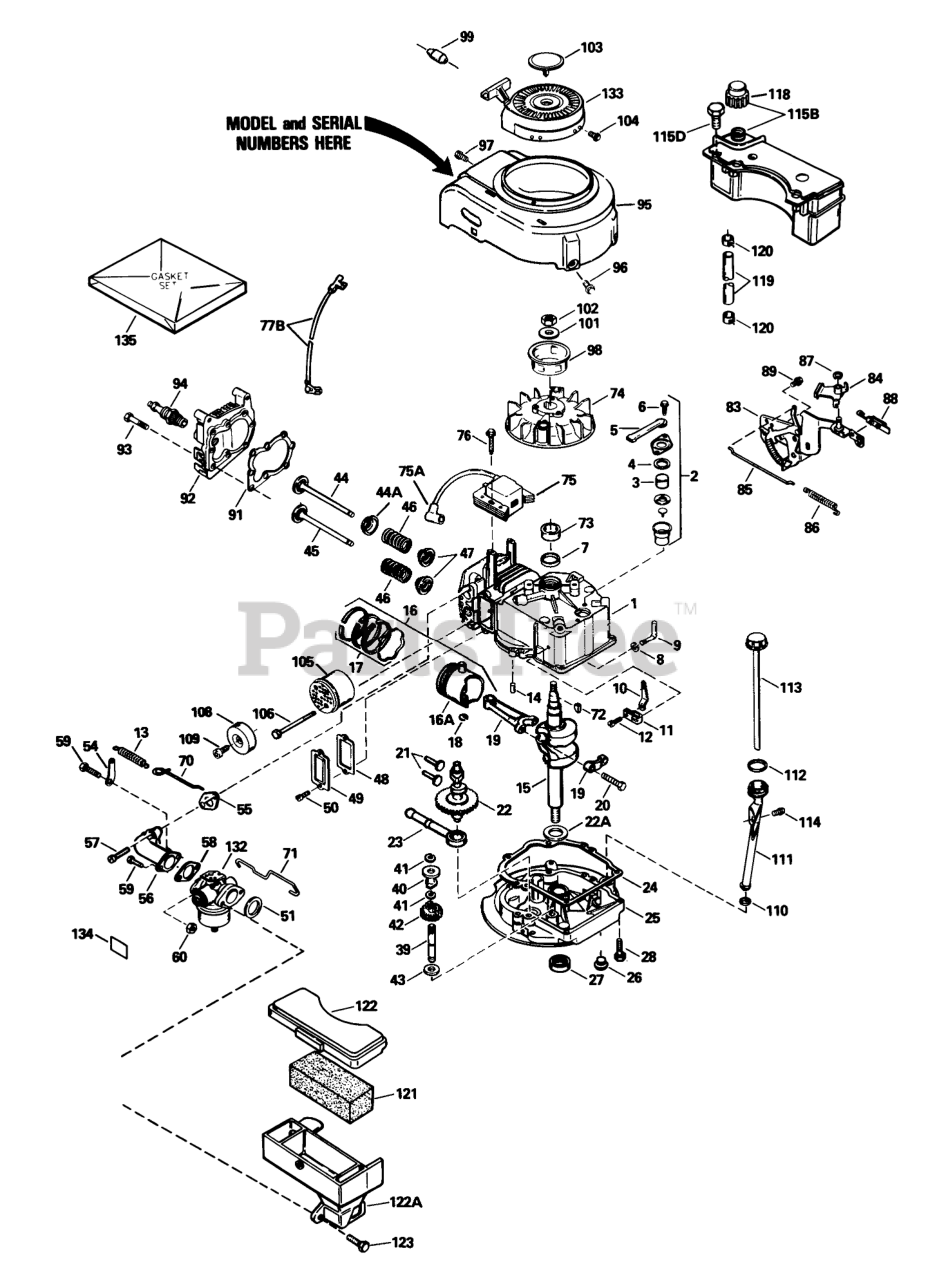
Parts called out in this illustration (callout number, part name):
1	Cylinder Assembly (Incl. Ref. #4, 6, 7 & 14)
2	Breather Assembly (Incl. Ref. #3 thru 6)
3	Element-Breather
4	Gasket-Breather
5	Tube, Breaker
6	Screw (10-24 x 9/16)
7	Seal-Oil
8	Washer-Flat
9	Rod, Governor (Incl. Ref. #8)
10	Governor Lever
11	Clamp-Lever, Governor
12	Screw
13	Spring Governor
14	Pin-Dowel
15	Crankshaft
16	Piston, Pin & Ring Assembly (Std.) (Incl. Ref. #16A, 17 & 18)
16	Piston, Pin & Ring Assembly (.010 oversize) (Incl. Ref. #16A, 17 & 18)
16	Piston, Pin & Ring Assembly (.020 oversize) (Incl. Ref. #16A, 17 & 18)
16A	Piston & Pin Assembly (Std.) (Incl. Ref. #18)
16A	Piston & Pin Assembly (.010 oversize) (Incl. Ref. #18)
16A	Piston & Pin Assembly (.020 oversize) (Incl. Ref. #18)
17	Piston Ring Set Std.
17	Piston Ring Set .010 O.S.
17	Piston Ring Set .020 O.S.
18	Ring-Retaining, Piston Pin
19	Rod Assembly, Connecting (Incl. Ref. #20)
20	Bolt-Rod, Connecting
21	Lifter-Valve
22	Camshaft(Mech.Comp. Release)
22A	Washer-Thrust
23	Oil Pump ASM
24	Gasket
25	Flange, Mounting (Incl. Ref. #26, 27 & 39)
26	Plug Oil Drain
27	Seal-Oil
28	Screw (1/4-20 x 1-1/4)
39	Shaft-Governor
40	Spool-Governor
41	Ring-Retaining
42	Gear Assembly, Governor (Incl. Ref. #43)
43	Washer
44	Valve, Intake (Std.) (Incl. Ref. #47)
44	Valve, Intake (1/32" oversize) (Incl. Ref. #47)
44A	Seal Assy., Intake
45	Valve, Exhaust (Std.) (Incl. Ref. #47)
45	Valve, Exhaust (1/32" oversize) (Incl. Ref. #47)
46	Spring-Valve
47	Cap-Valve, Spring
48	Gasket-Cover, Valve
49	Cover-Valve
51	Gasket-Cleaner, Air
54	Lever-Adjusting, R P M
55	Gasket-Intake Pipe
56	Pipe, Intake (Incl. Ref. #55)
57	Screw (1/4-20 x 1)
59	Screw (1/4-28 x 7/8)
60	Nut and Lock Washer (1/4-28)
70	Link-Governor
71	Link-Throttle
72	Key-Flywheel
74	Flywheel
75	Solid State
75A	Cover-Spark Plug
76	Screw
77B	Ground Wire
83	Bracket-S.E. Brake
84	Lever-Brake
85	Link-Control
86	Spring-Extension
87	Ring-Retaining
88	Terminal
89	Screw (1/4-20 x 3/8)
91	Gasket-Cylinder Head
92	2025A67 ADD.ASSEMBL
93	Screw (5/16-18x1-1/2)
94	Spark Plug-Resistor (R J19 L M)
95	Housing-Blower
96	Screw (1/4-20 x 1/2)
97	Screw (10-24 x 9/16)
98	Hub-Starter
99	Retainer-Starter Rope
101	Washer-Belleville
102	Nut-Flywheel
103	Plug Starter
104	Screw, Hex Hd.
105	Muffler Assembly (Incl. Ref. #106)
108	Cover-Muffler
109	Screw (8-32 x 3/8)
111	Oil Fill Tube
113	Dipstick
114	Screw (10-32 x 1/2)
115B	Tank Assembly (Incl. Ref . #118)
115D	Screw (10-32 x 35/64)
118	Cap-Fuel
119	Line-Fuel
120	Clamp-Line, Fuel
121	Filter-Air Cleaner
122	Cover-Air Cleaner
122A	Body Air cleaner
132	Carburetor (Incl. Ref. #58)
133	Starter-Rewind
134	Decal-Primer
135	Gasket Set (Incl. items marked )
